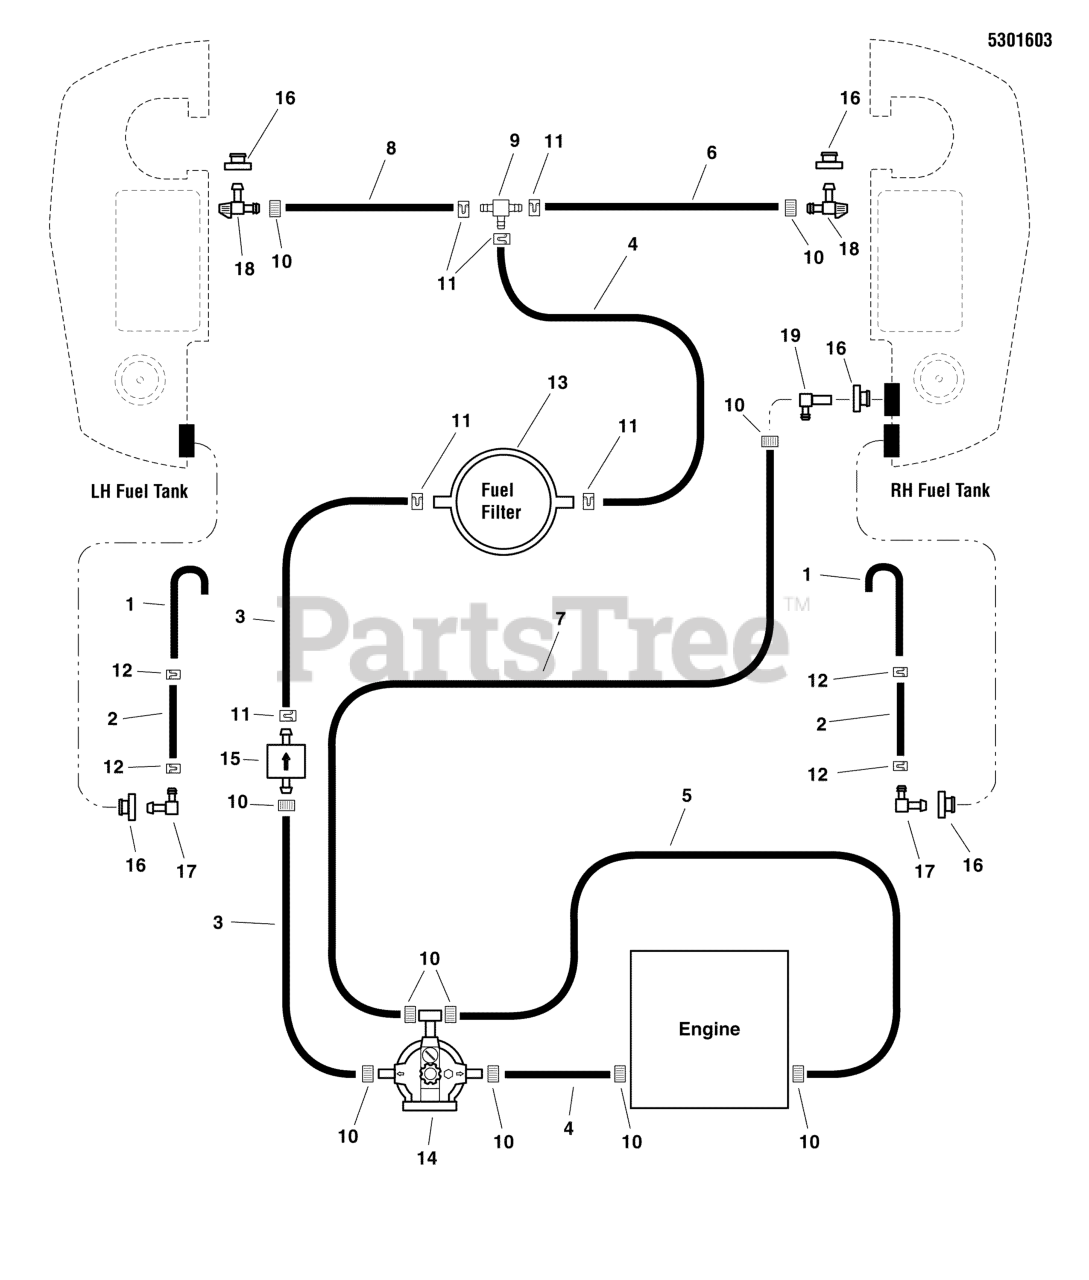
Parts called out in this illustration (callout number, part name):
1	VENT TUBE, DIESEL
2	HOSE, 1/4" FUEL, 25.00"
3	FUEL HOSE, 5/16 ID X 2.50
4	FUEL HOSE, 5/16 ID X 14.00
5	FUEL HOSE, 5/16 ID X 19.00
6	FUEL HOSE, 5/16 ID X 22.00
7	FUEL HOSE, 5/16 ID X 25
8	FUEL HOSE, 5/16 ID X 42.00
9	FITTING, TEE, 5/16 HOSE
10	CLAMP, #4 HOSE, STAINLESS
11	CLAMP, HOSE, EXTERNAL, 9/16
12	CLAMP, HOSE, EXTERNAL, 1/2 - RED
13	STRAINER, FUEL (IN-LINE)
14	ASSY, FUEL FILTER/WATER SEP.
15	PUMP ASSY, FUEL FEED
16	BUSHING-FUEL TANK RED RUBBER
17	FITTING, DAPCO, 3/8" 90 DEGREE (SV)
18	VALVE, FUEL SHUT-OFF, 11408 (SV)
19	FITTING, 5/16 X .40, 90 ELBOW DAPCO. (SV)
